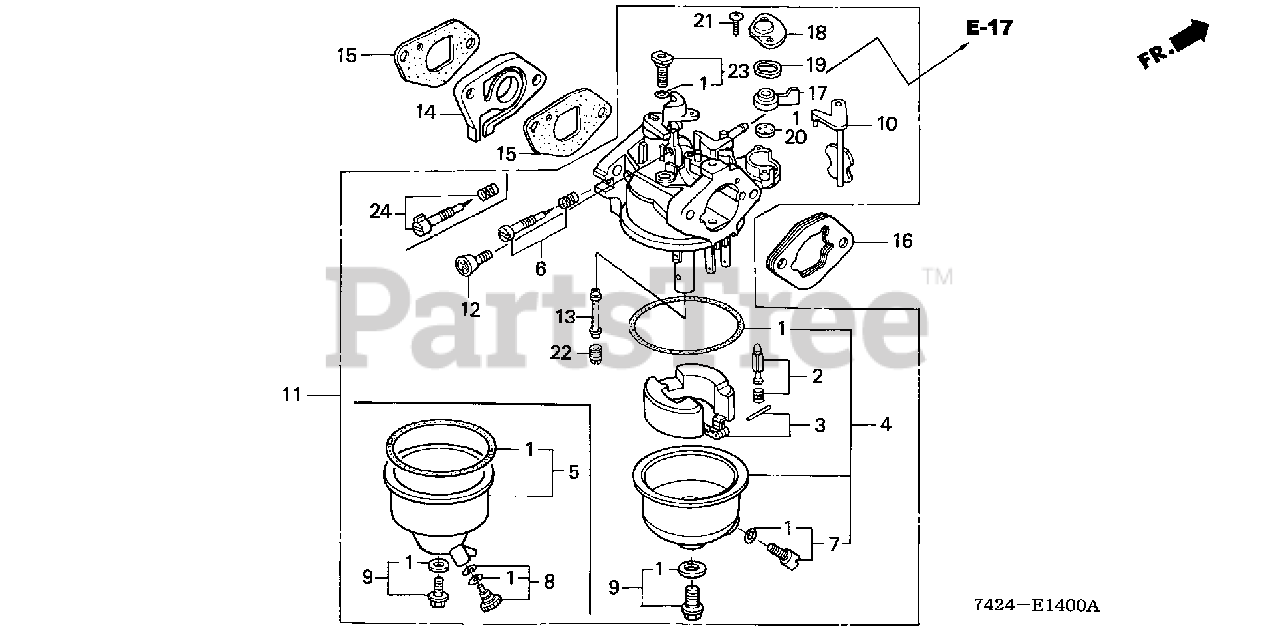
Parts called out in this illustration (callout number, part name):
1	GASKET SET (CARBURETOR NO.)
2	VALVE SET, FLOAT
5	CHAMBER SET, FLOAT (CARBURETOR NO.)
6	SCREW SET, PILOT
8	SCREW SET, DRAIN (CARBURETOR NO.)
9	SCREW SET B
10	CHOKE SET (CARBURETOR NO.)
11	CARBURETOR ASSY. (BE03B E)
12	SCREW, THROTTLE STOP
13	NOZZLE, MAIN
14	INSULATOR, CARBURETOR
15	GASKET, INSULATOR
16	SPACER, CARBURETOR
17	LEVER, VALVE (CARBURETOR NO.)
18	PLATE, LEVER SETTING (CARBURETOR NO.)
19	SPRING, VALVE LEVER
20	GASKET, VALVE (CARBURETOR NO.)
21	SCREW, PAN (3X8)
21	SCREW, PAN (3X6)
22	JET, MAIN (#58) (CARBURETOR NO.)
22	JET, MAIN (#60) (CARBURETOR NO.)
22	JET, MAIN (#62) (CARBURETOR NO.)
22	JET, MAIN (#58)
23	JET SET, PILOT (#35)
